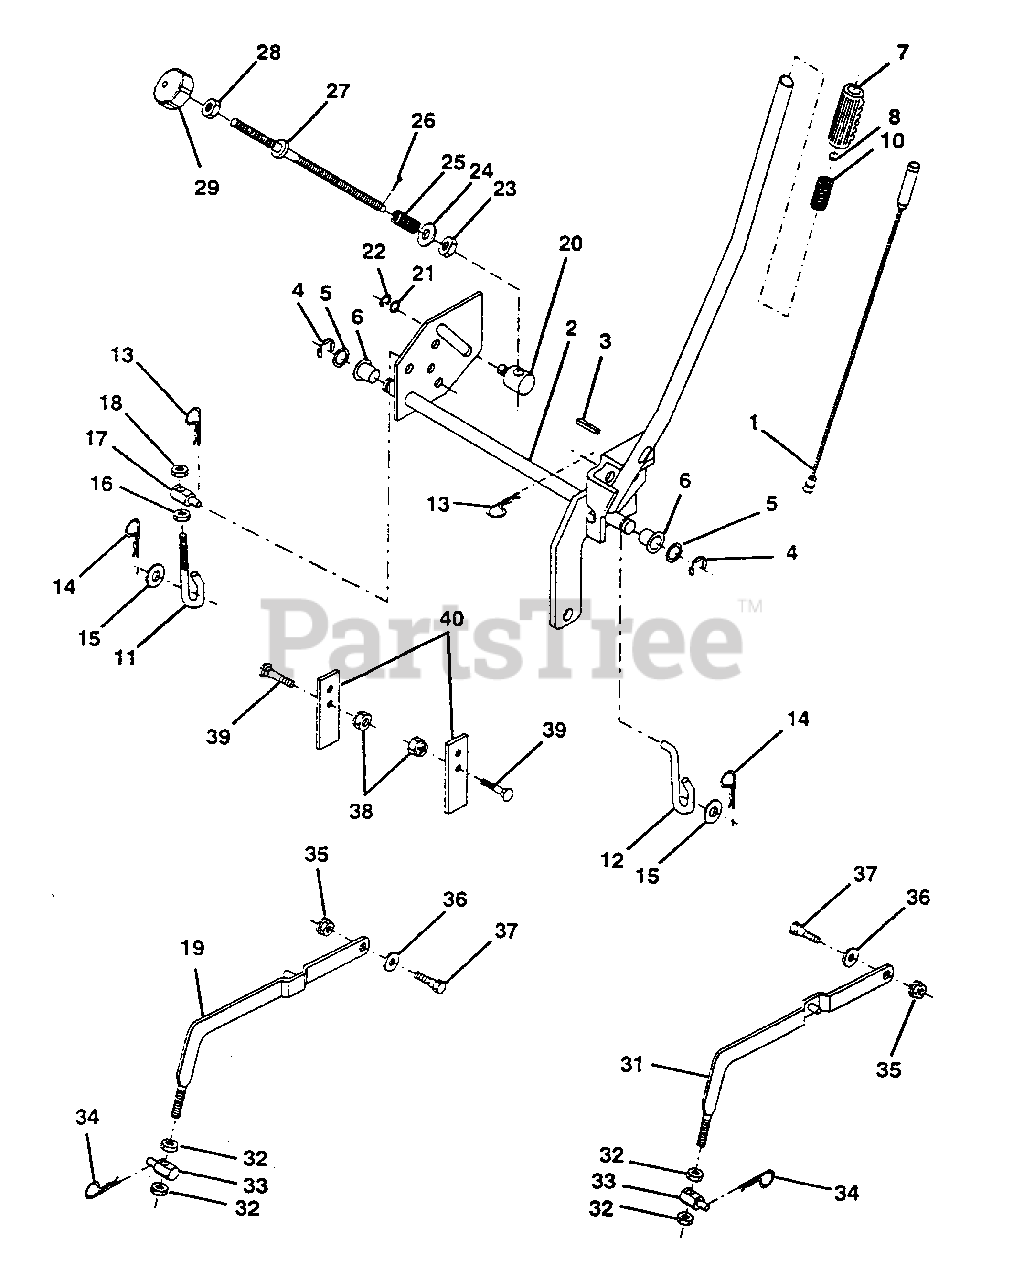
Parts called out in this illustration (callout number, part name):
1	Wire Asm Inner W/Plunger 20 56
2	Shaft Asm Lift RH w/Inf W/T
3	Pine Groove 1 500 Zinc
4	E Ring #5133-62
5	Washer 21/32 x 7/8 x 16 Ga.
6	Bearing Nylon Bld 629 Id
7	Grip Handle Fluted Blk
8	Button Plunger Black
10	Spring Cprsn 3 750 Oiled
11	Link, Lift LH
12	Link, Lift RH
13	Retainer Spring
14	Retainer Spring
15	Washer 17/32 x 15/16 x 16 Ga.
16	Nut Hex 7/16-20 UNF
17	Trunnion Lift
18	Nut, Crownlock 7/16-20
19	Arm Suspension LH 44"
20	Retainer Spring
21	Washer 15/32 x 3/4 x 16 Ga.
22	Ring Klip #t5304-37
24	Washer 13/32 x 5/8 x 16 Ga.
25	Spring 2-1/8"
26	Pin Cotter 3/32 x 1/2
27	Rod Adj Lift Zinc 9 00 Wrk Lg
28	Nut Hex Jam 3/8-16 Unc
29	Knob Inf 3/8-16 Unc Blk W/sym
30	Trunnion Dp Stop Dbl Thds PLT
31	Arm. Asm. Suspension RH 44"
32	Nut Hex 1/2-13 Unc
33	Trunnion Lift Lower
34	Retainer Spring
35	Nut Crownlock 3/8-16
36	Washer, Spring, Oiled
37	Bolt Shoulder 3/8-16
38	Nut, Crownlock 3/8-16
39	Bolt Carriage 3/8-16 x 1
